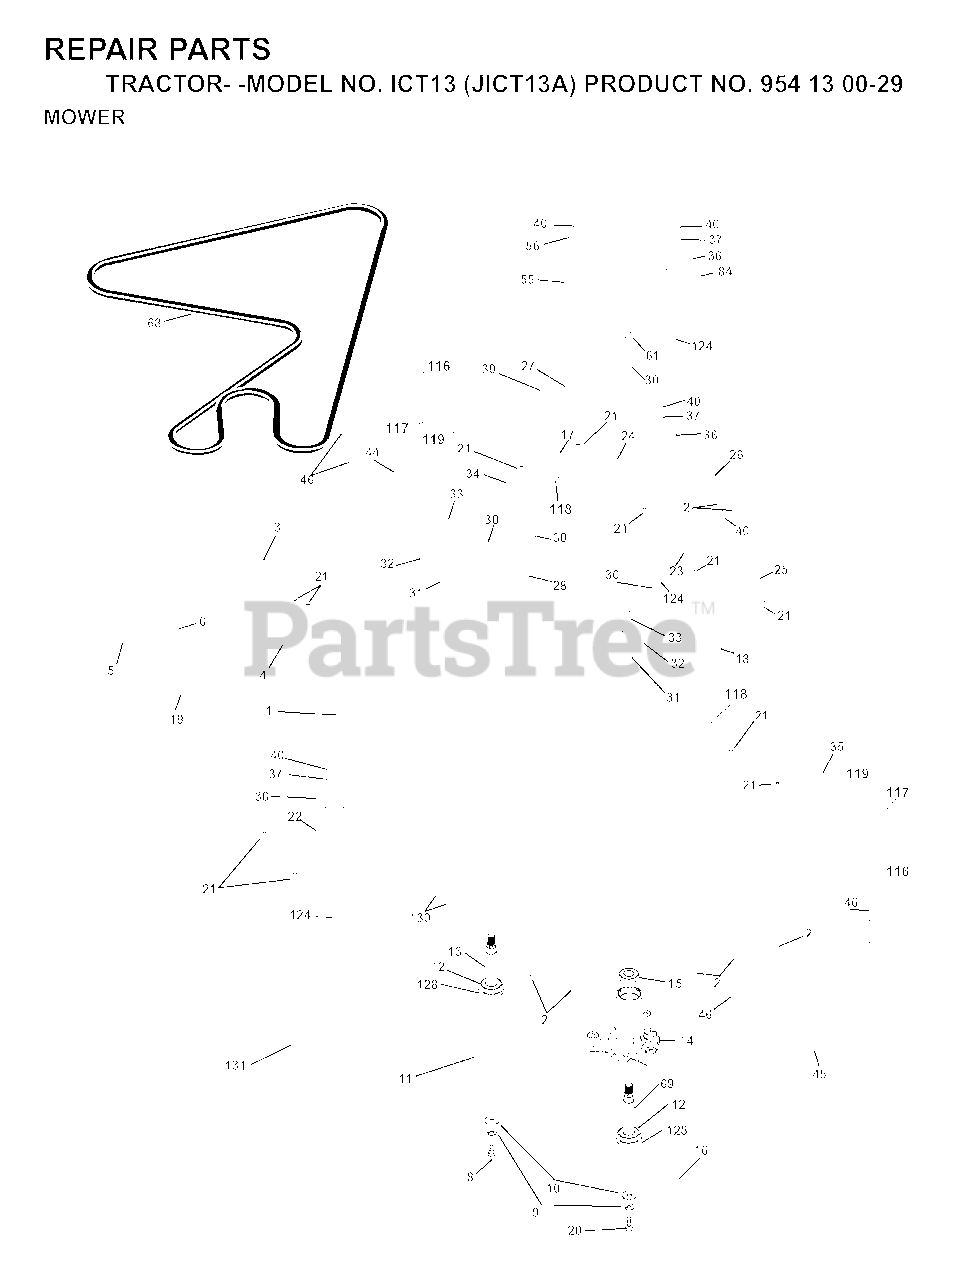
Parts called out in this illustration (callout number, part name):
1	MOWER HOUSING, DECK
2	BOLT
3	BRACKET
5	RETAINER-SPRNG RB
6	BAR SWAY
8	BLADE BOLT
9	LOCKWASHER
10	WASHER.BLADE
11	BLADE
12	BEARING
13	SHAFT ASM VENT
14	HSG MANDREL
16	BLADE
17	BOLT.3/8-14X1.25
19	BOLT SHD 5/16-18
21	LOCKNUT
24	BRACKET
25	BRACKET
26	BRACE
28	BRACKET
30	SCREW THDROL ROLLING WASHER HD
31	WASHER
32	PULLEY, MANDREL
33	NUT
36	PULLEY.IDLER.4.25
40	LOCKNUT
45	COVER
46	SCREW.1/4-20X5/8
55	ARM IDLER
56	SPACER RETAINER
61	SPRING.TENSION.BELT
68	HEX-BELT 92 MOWER 105AA
69	SHAFT.ASM.W/LWR.BRG.RH.THREAD
84	KEEPER, BELT IDLER
116	BOLT, SHOULDER
117	WHEEL GAGE DONUT
118	LOCKNUT
119	WASHER
124	BOLT.3/8-16X1.50
128	WASHER FELT
131	CHUTE BAGGER
